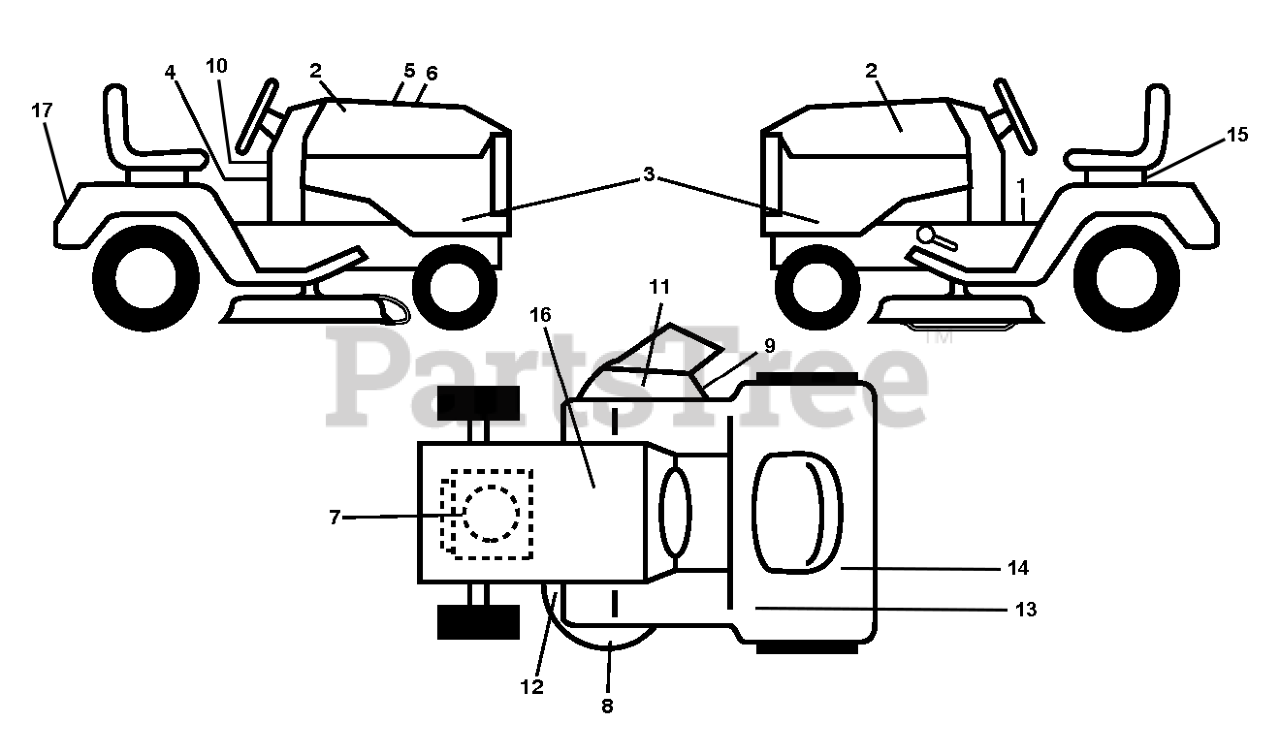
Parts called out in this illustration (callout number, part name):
1	DECAL.FENDER.WARNING.ENG
1	DECAL.FENDER.WARNING.ENGLISH
1	DECAL.WARNING.2007.ENG/FR
1	DECAL.WARN.STARTINST.LOWEARIEN
2	DECAL.BADGE.170MM.TEXTLOGO.
2	RP.DECAL.BADGE.170MM.TEXTLOGO
2	DECAL HOOD
2	DECAL.WB.178MM.15.HUSQ.NEWBRAN
3	DECAL.SDPNL.YTH22V46.BS.HUSQ
3	DECAL.SIDE.PANEL.YTH22V46.2013
3	RP.DECAL.BADGE.170MM.TEXTLOGO
4	DECALS.WARN.CA.SPKARREST/PROP
4	DECAL, WARNING SPARK ARRESTOR
5	DECAL.WARNING.CUST.RESP.E85.
6	DECAL.RPL.BSM40.TLW.46.K46
6	Decal, Replacement
6	DECAL.RPL
6	DECAL.ETHANOL.E85 WARNING SYMB
6	DECAL.RPL.BSM44.END.TLW.46C.K4
6	DECAL.ENG.BS.22INTK.DOM.381708
6	DECALS
6	NULL
6	DECAL.RPL.
6	DECAL.RPL.BSM44.INTK.TLW.46,
6	DECAL.RPL.BSM.44.INTK.TLW.46
6	DECAL.E85.WARNING.2012
6	DECAL.RPL.BSM44.INTK.TLW.46.K4
7	DECAL.ENGINE.B&S
7	Decal, Engine H.P.
7	DECAL.ENG.BS.22INTK.DOM.381708
7	DECAL DECAL.ENG.BS.ENDUR.22HP.
7	DECAL.ENG.BS.22HP.INTK
7	DECAL.ENG.BS.HUSQ.22HP.382212
8	DECAL
9	DECAL.MOWER.WARN.KEEP.HAND.AWY
9	DECAL, DECK DEFLECTOR, WARNING
9	DECAL.DECK.STAMP.BIOCLIPCMP.HU
9	DECAL.WARN.KEEP.HAND.AWAY
10	LABEL.EMISS.CALIF.HUSQVARNA
11	DECAL, DECK DEFLECTOR, WARNING
11	DECAL.DECK.DEFLECTOR.WARNING
12	DECAL.DECK.BELT.ROUTE.42"2021
12	DECAL.V-BELT.SCH.42/46"MEC/ELE
13	DECAL.E85.WARNING.2012
13	DECAL.DECK.BUILTINAMERICA.HUSQ
14	DECALS
15	DECAL BTRY SYMBOLS
16	DECAL BTRY SYMBOLS
17	DECAL.FENDER
